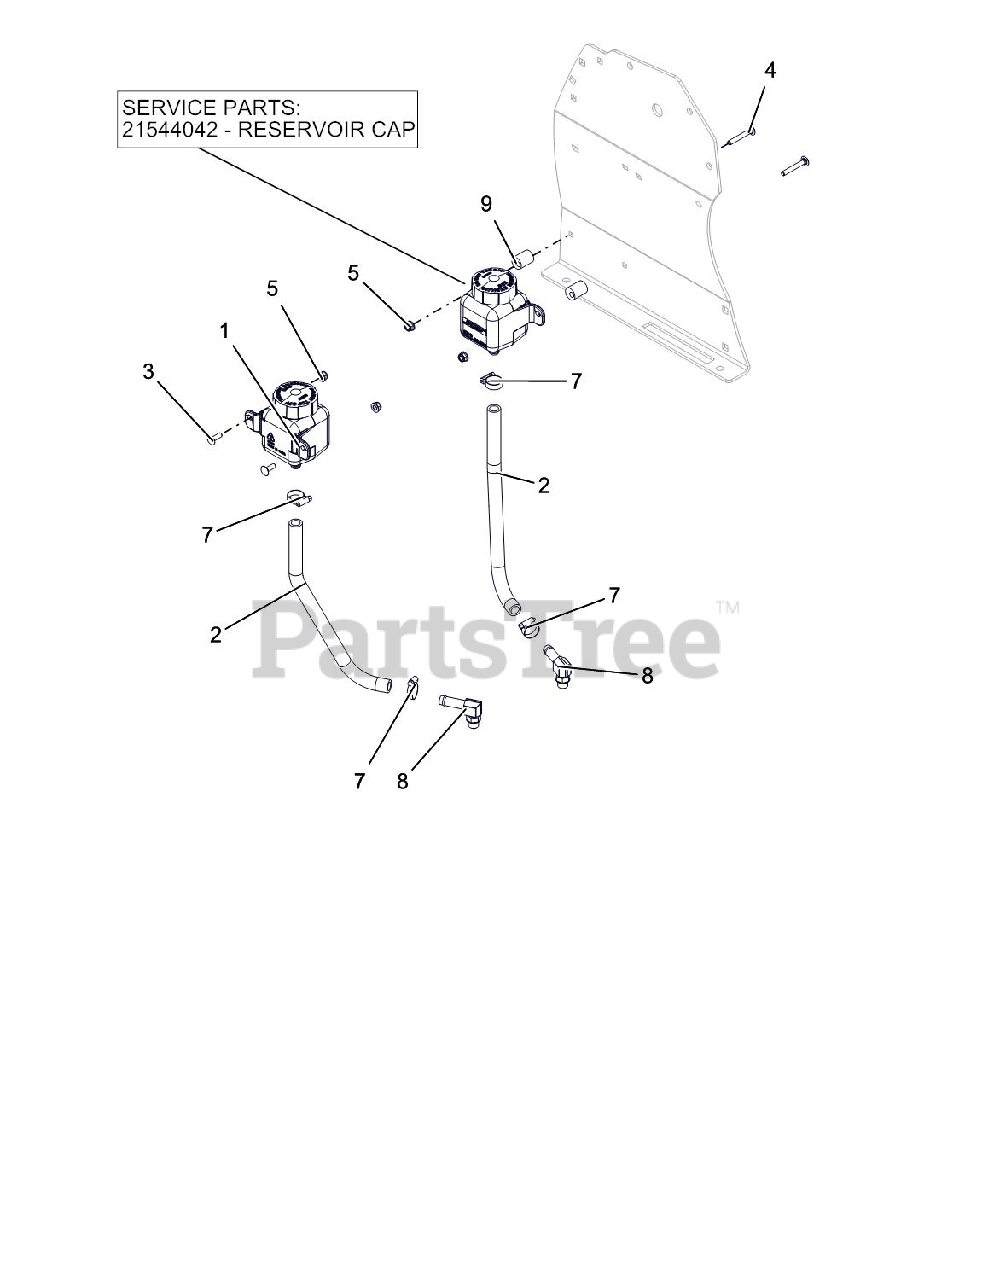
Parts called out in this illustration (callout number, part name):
1	TANK, EXPANSION
1	CAP, HYDRO RESERVOIR REPLAC.
2	HOSE, PROSTANCE HYDRO OVERFLOW
3	@BLT-RDHDSQNK .25-20X.75 G5YZ
4	BLT-RDHDSQNK .25-20X1.75 G5YZ
5	@NUT-LK-NYL-FLG .25-20 YWZC
7	CLAMP,.88 DIA. HOSE
8	FITTING, HYD (90 DEG)
9	ECCENTRIC
